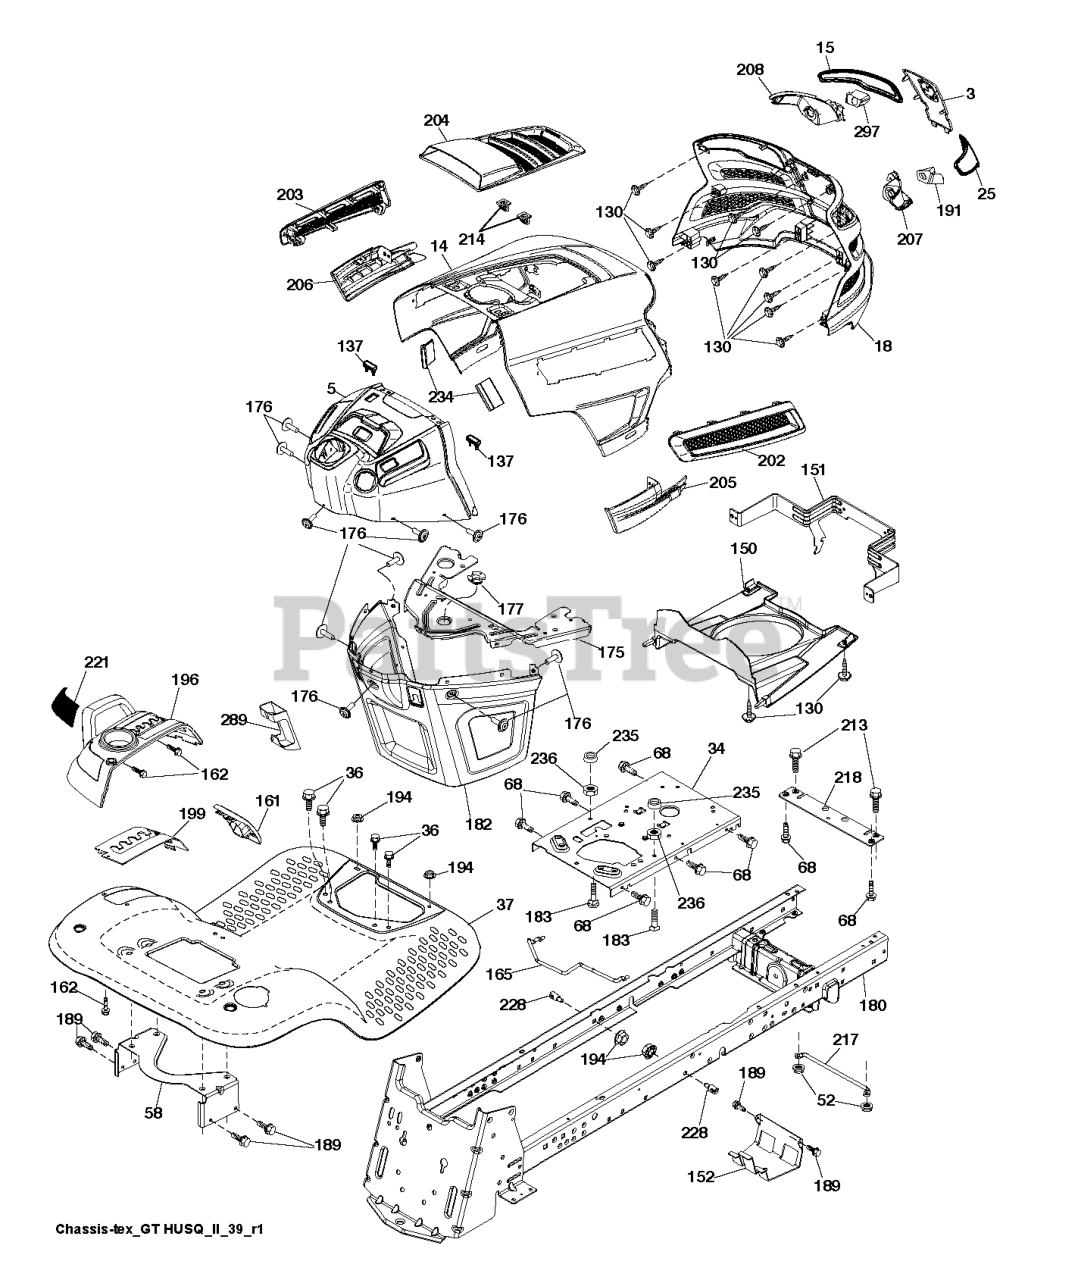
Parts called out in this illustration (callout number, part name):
3	APPLIQUE.SUBASM.GT.HUSQ.II
5	DASH.UPP.GT2.SM.PTO.MCHOKE
14	HOOD.ASM.HUSQVARNA.GT.TEX.ORAN
15	LENS.HEADLIGHT.LH.GTII.2011
18	GRILLE.SUBASM.GT.HUSQ.II
25	LENS.HEADLIGHT.RH.GTII.2011
34	PLATE PLATE ENGINE
36	SCREW 5/16"
37	FENDER.PNT.TX.GT.CH/FW/DL.HUSQ
52	LOCKNUT
58	BRKT.SUPPORT.FNDR/TANK
68	Screw 5/16-18 x 1/2 Hex, Self Tapping 5/16-18 x 1/2
130	SCREW.#10 X 0.750.BOS
137	BUMPER DASH
150	AIR.DUCT.GTV.BLACK
151	BRACKET.PIVOT.HOOD.GT.HUSQ.II
152	SHIELD.BROWNING.W/TEX
161	CONSOLE.FUEL.WINDOW.HU
162	SCREW.HI-LO.CONSOLE
165	SUPPORT.TANK.REAR.W/TEX
175	PLATE.CROSSMEMBER.HUSQ
176	SCREW.#10-24X5/8.RN.QU
177	BUSHING, STEERING
180	CHASSIS.GT.SLOPED.DRAWBAR.
182	DASH.LOWER.COMMON.12V.ADAPTOR
183	BOLT.5/16-18X1-1/4 FULL THD
189	SCREW
191	INSERT.REFLECTIVE.RH.HUSQ.GTII
194	NUT LOCK HEX FLANGE 5/16-18
196	SUBASM.CONSOLE.HUSQ.GT.DECKLFT
199	PLATE.DECK.LIFT.HUSQVARNA.GT
202	VENT.SIDE.RH.GT.HUSQ.II.
203	VENT.SIDE.LH.GT.HUSQ.II.498
204	VENT.TOP.HUSQ.GT2
205	SIDE.TRIM.RH.GT.HUSQ.II
206	SIDE.TRIM.LH.GT.HUSQ.II.GRAY
207	BEZEL LIGHT.RH.GT.II.MYLAR
208	BEZEL LIGHT.LH.GT.II.MYLAR
213	BOLT
214	CLIP.RETAINER.TINNER.
217	ROD.PIVOT.HOOD
218	X-PIECE.HOOD.STOP.NON/
221	REFLECTOR.LH.TEX GT HU
228	STUD.FASTNER.W/ANTI-ROTATE
234	BUMPER.HOOD.TEX.HUSQVARNA
235	SPACER FENDER
236	NUT.CENTERLOCK.5/16-
289	PLUG.N/CRUISE.COMMON.YT/GT.BLK
297	INSERT.REFLECTIVE.LH.HUSQ.GTII
